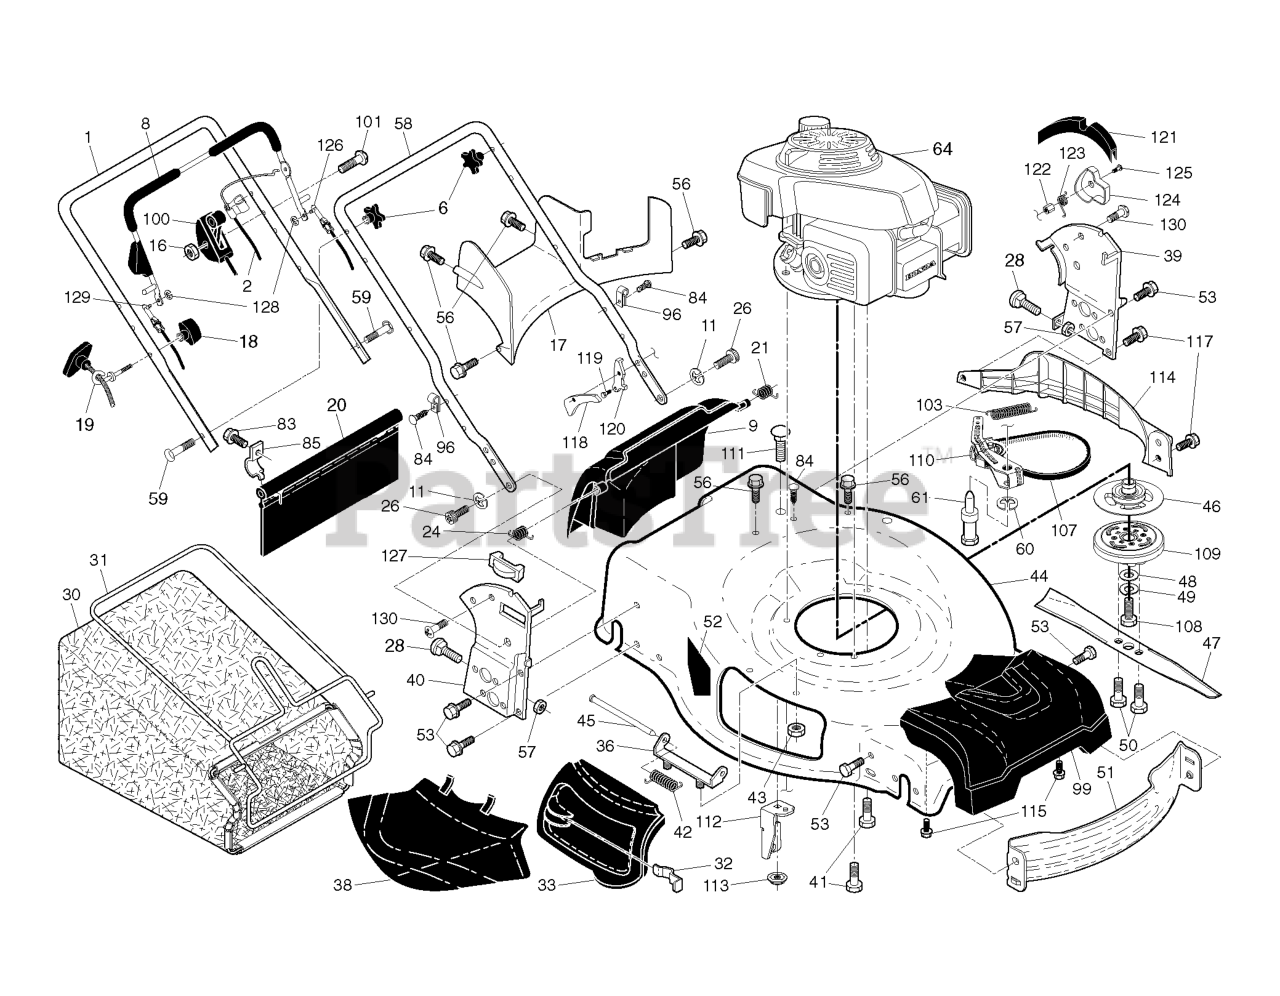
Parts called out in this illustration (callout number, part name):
1	HANDLE.UPPER.3.POS.BS.AW2.GREY
2	CABLE.BBC.22+.AW2.BS.ERGO.WALK
6	KNOB.HANDLE.PLASTIC.STAR.BLACK
8	BAIL.ARM ASM.ERGO OM.ORG/BLK
9	DOOR.REAR.ASM.22+GEN.FG/RG.498
11	E-RING.12MM.SHAFT
16	NUT
17	BAFFLE.REAR.22+RGD.AWD.PLASTIC
18	T-KNOB.NEW ROPE GUIDE
19	GUIDE.ROPE.BLK.ZINC.CHROM
20	SKIRT.REAR.22+RGD.HIGH WHEEL
21	SPRING.LH.BLACK
24	SPRING.RH.GRAY
26	SCREW,DOOR/HANDLE.PIVOT
28	BOLT.CARRIAGE.LN.5/16-18X.5/8
30	GBAG.BA85028EM.NOFRAME.GRY/SLV
31	FRAME.GBAG.22+.BLK
32	LATCH.DOOR.ZINC
33	DOOR.MULCH.22 PLUS.HUSQ.GREY
36	BRACKET.ASM.HINGE.21.FWGD.
38	DEFLECTOR.CLIPPING.22.BLACK
39	BRACKET.ASM.HANDLE.LT.22+.498
40	BRACKET.ASM.HANDLE.RT.22+.498
41	BOLT 3/8-16X1-1/8
42	SPRING.TORSION
43	NUT.FLANGE.1-4-20-SERR
44	KIT.HSG.22+AW.MC.WO.BBC.STB
45	ROD.HINGE.21
46	PULLEY.BBC.DRIVING
47	BLADE.22.REAPER.BBC.RUST PREVE
48	WASHER.CRANK.BOLT
49	LOCKWASHER
50	BOLT.BLADE
51	BAFFLE.FRONT.22.PLUS
52	DANGER DECAL
53	BOLT.5/16HEX.WHS.HD
56	SCREW.HX.13X.750
57	NUT.FLANGE.5/16
58	HANDLE.LOWER.22+EZS.498
59	BOLT, HANDLE 5/16-18X1.75
60	E-RING.12MM.SHAFT
61	BOLT.BBC.TENSION.PIVOT
83	TAPPING SCREW
84	FASTENER.PUSH.O.250X0.783
85	BRACKET.SKIRT.22+.BZP
96	CLIP.CABLE.BLK
99	COVER.ASSEMBLY.FRONT.22+AWD
100	CONTROL.THROTTLE.BBC.HON.22+AW
103	SPRING.BRAKE.RESET
107	BELT.COG.BBC
108	SCREW, HEX HD 3/8-24 X 1-3/8
109	HUB.FREE.BBC.ASSEMBLY(2 2MC)
110	ARM.BBC.TNSION.ARM.PULL(2 2MC)
112	BRACKET.CABLE MOUNTING.22+
113	NUT.FLANGE.1-4-20-SERR
114	BUMPER.LEFT SIDE 22+.498
115	SCREW.HI-LO. 5/16 X 1.00
117	BOLT.HEX.HD.WASHER.5/16-18X.75
118	COVER.INSIDE.LOWER.LT.EZS
119	BOLT.PAWL.M6
120	PAWL.ADJUSTMENT.EZS.LEFT
121	BRACKET.BAG.ASM.EZS.LH.BLK
122	NUT.PAWL.M6
123	SPRING.TORSION.PAWL ENG.LT
124	COVER.OUTSIDE.LOWER.EZS.LT
125	SCREW.TORX.PAN HEAD.M6-1
126	CABLE.EBA.ACTUATION.LT.BBC.MOW
127	DOOR.REAR.LIFT.ASM EZS
128	E-RING.5/32.HD
129	CABLE.EBA.ACTUA.RT.BBC.ERGOHD
130	SCREW.PAN.HEAD.#10
